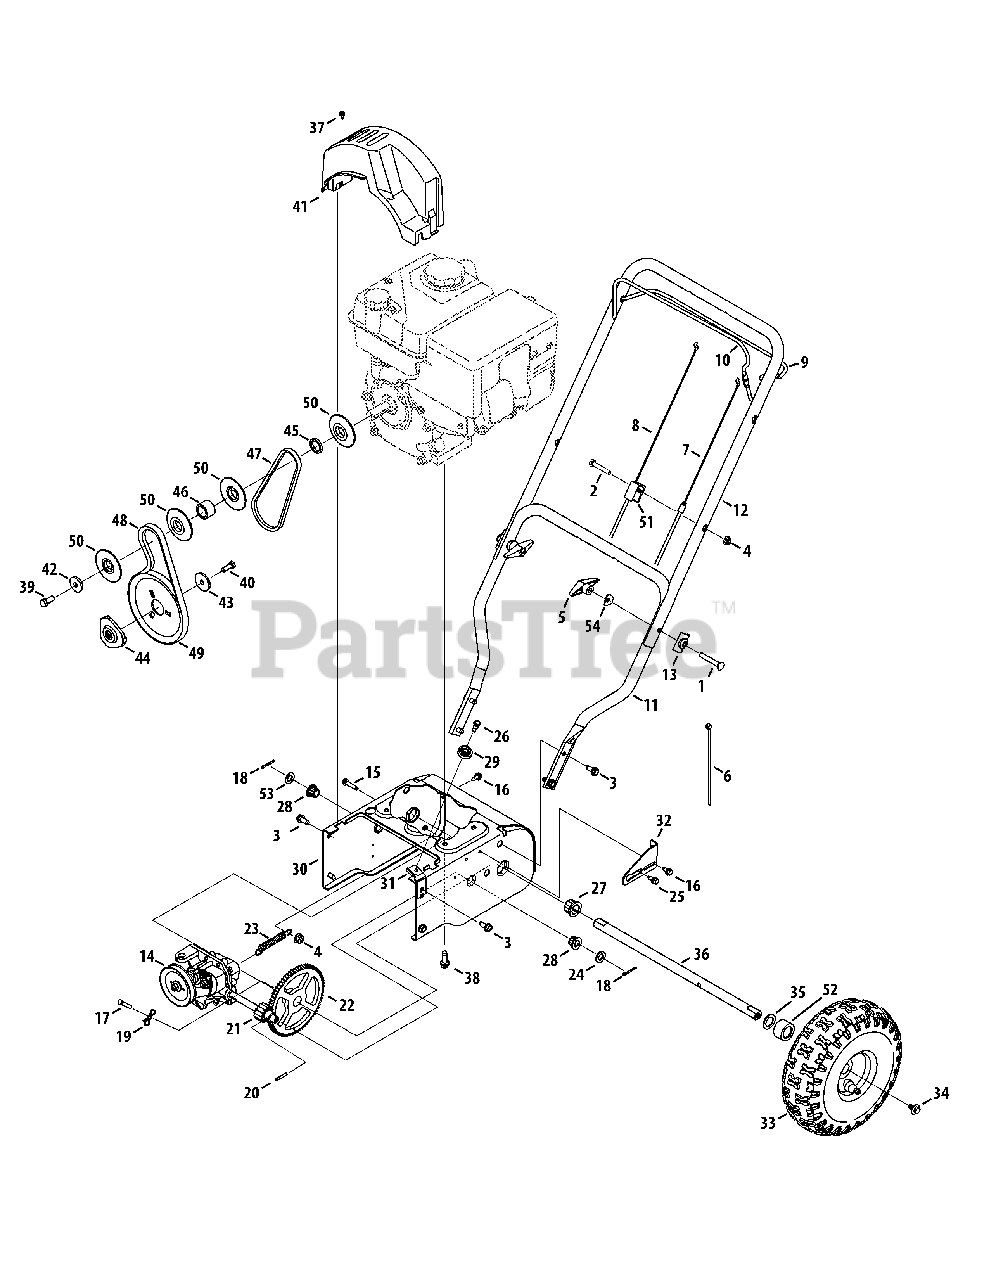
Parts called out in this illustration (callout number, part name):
1	Carriage Screw, 5/16-18 x 2.25
2	Mach. Screw, 1/4-20 x 1.50
3	Screw, 5/16-18 x .75
4	Flange Lock Nut, 1/4-20
5	Wing Knob, 5/16-18
6	Cable Tie
7	Drive Cable
8	Auger Cable
9	Drive Control
10	Auger Control
11	Lower Handle
12	Upper Handle
13	Handle Tab
14	Transmission Assembly
15	Self-Tapping Screw, 1/4-20 x 1.25
16	Screw 1/4-20 x .625
17	Clevis Pin
18	Cotter Pin, 1/8 x 1.0
19	Bow Tie Cotter Pin, 72
20	Roll Pin
21	Pinion, 14T
22	Gear, 70T
23	Extension Spring
24	Flat Washer
25	Shoulder Screw, 1/4-20
26	Shoulder Screw, 1/4-28
27	Hex Flange Bearing
28	Hex Flange Bearing
29	Cable Roller
30	Drive Housing Frame
31	Auger Cable Bracket
33	Wheel Assy. ,Snow Hog, Gray
34	Screw, 5/16-24 x .750
35	Flat Washer, .793 x 1.24 x .06
37	Hex Screw, #10-16 x .500
38	Sems Screw, 3/8-16 x 1.0
39	Hex Bolt ,3/8-24 x .875
40	Lock Bolt, 5/16-24 x .875
41	Belt Cover
42	Flat Washer, .45 ID x 1.5 OD
43	Flat Washer, .34 ID x 1.50 OD
44	Pulley: Adapter ,.75 Dia.
45	Flat Washer, .876 x 1.25 x .11
46	Spacer, .876 x 1.25 x .94
47	V-belt, 3/8 x 21.108 Lg.
48	V-belt, 3/8 x 26.375 Lg.
49	Auger Pulley
50	Pulley Half
51	Cable Clip
53	Flat Washer, .53 x .93 x .05
54	Saddle Washer
